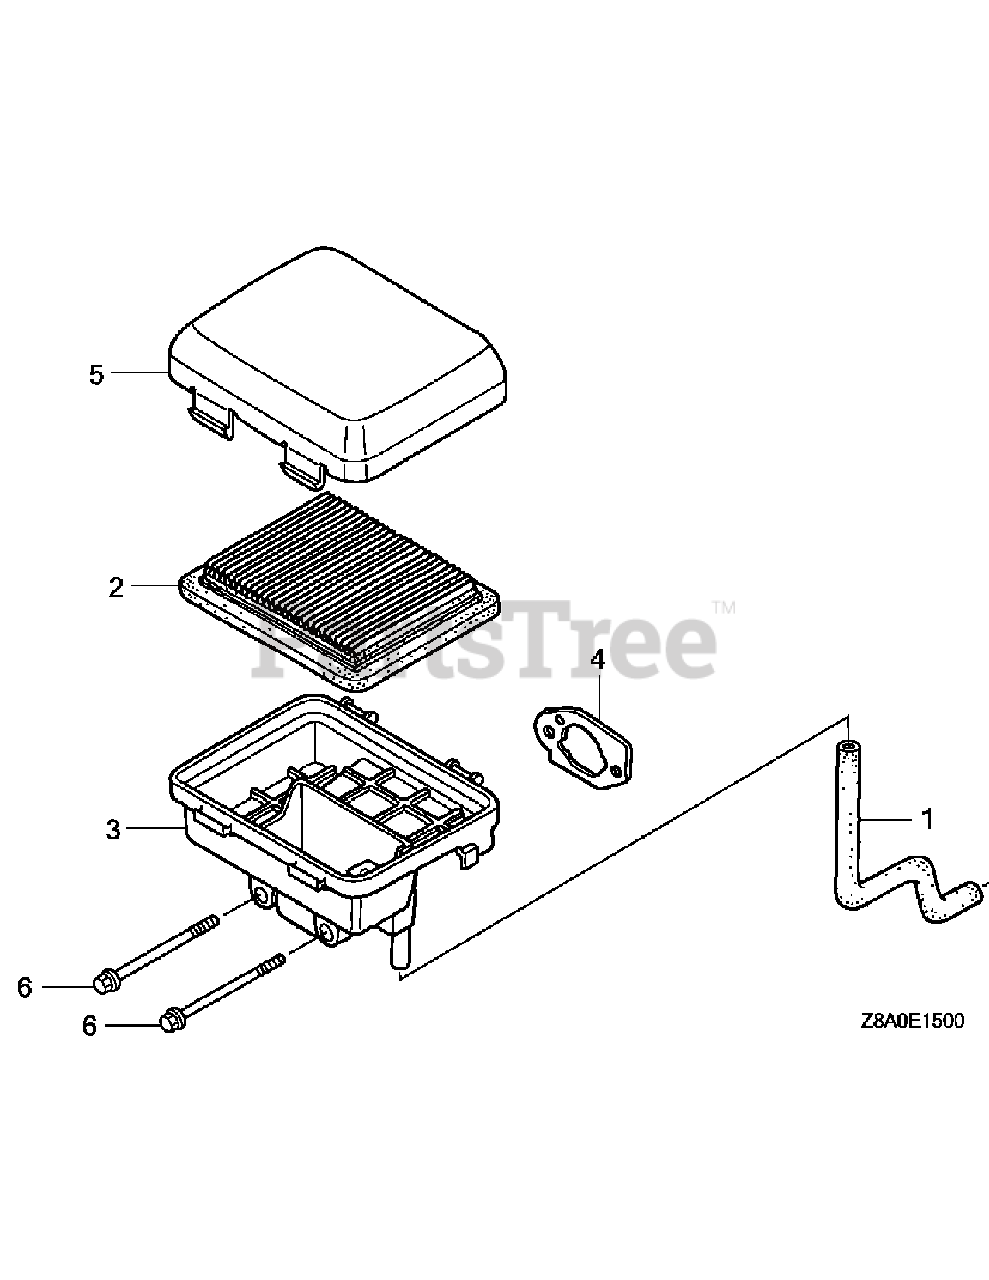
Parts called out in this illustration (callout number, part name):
1	Tube, Breather
2	Element, Air Cleaner
3	Case Complete, Air Cleaner
4	Packing, Air Cleaner
5	Cover, Air Cleaner
6	Bolt, Flange 6 x 112 (CT200)
